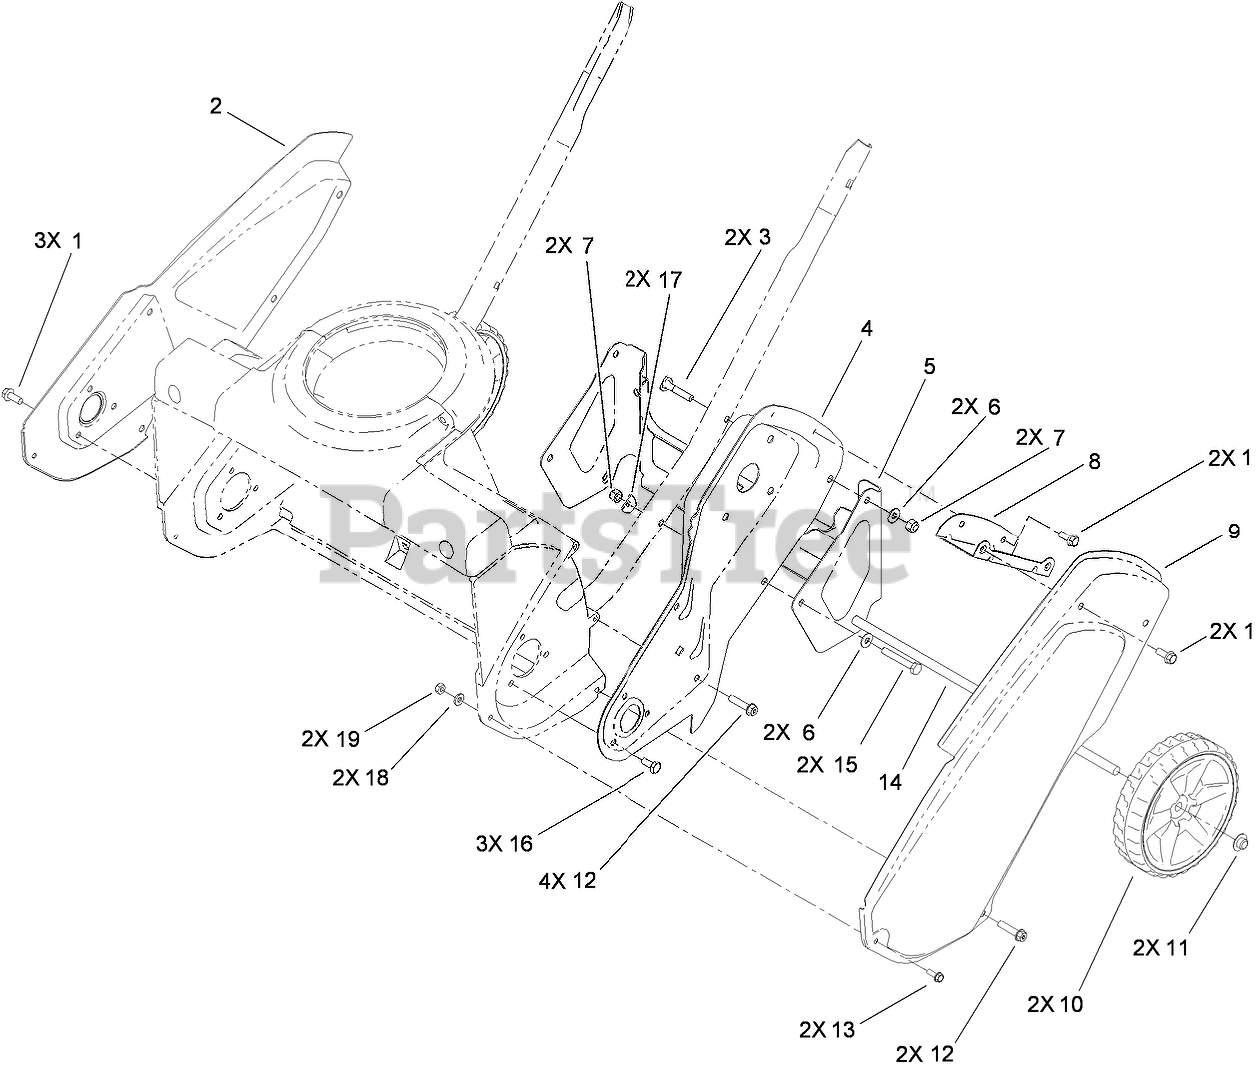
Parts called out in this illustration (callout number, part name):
1	SCREW-HWH
2	SIDEPLATE-RH
3	SCREW-HANDLE
4	SIDEPLATE-LH
5	BRACKET-WHEEL
6	WASHER-FLAT
7	NUT-LOCK, NI
8	BRACKET-COVER, BELT
9	COVER-BELT
10	WHEEL
11	RETAINER-PUSH ON
12	SCREW-PLASTIC
15	SCREW-HH
16	SCREW-HH, TAPTITE
17	WASHER
18	WASHER-FLAT
19	NUT-LOCK, NI
